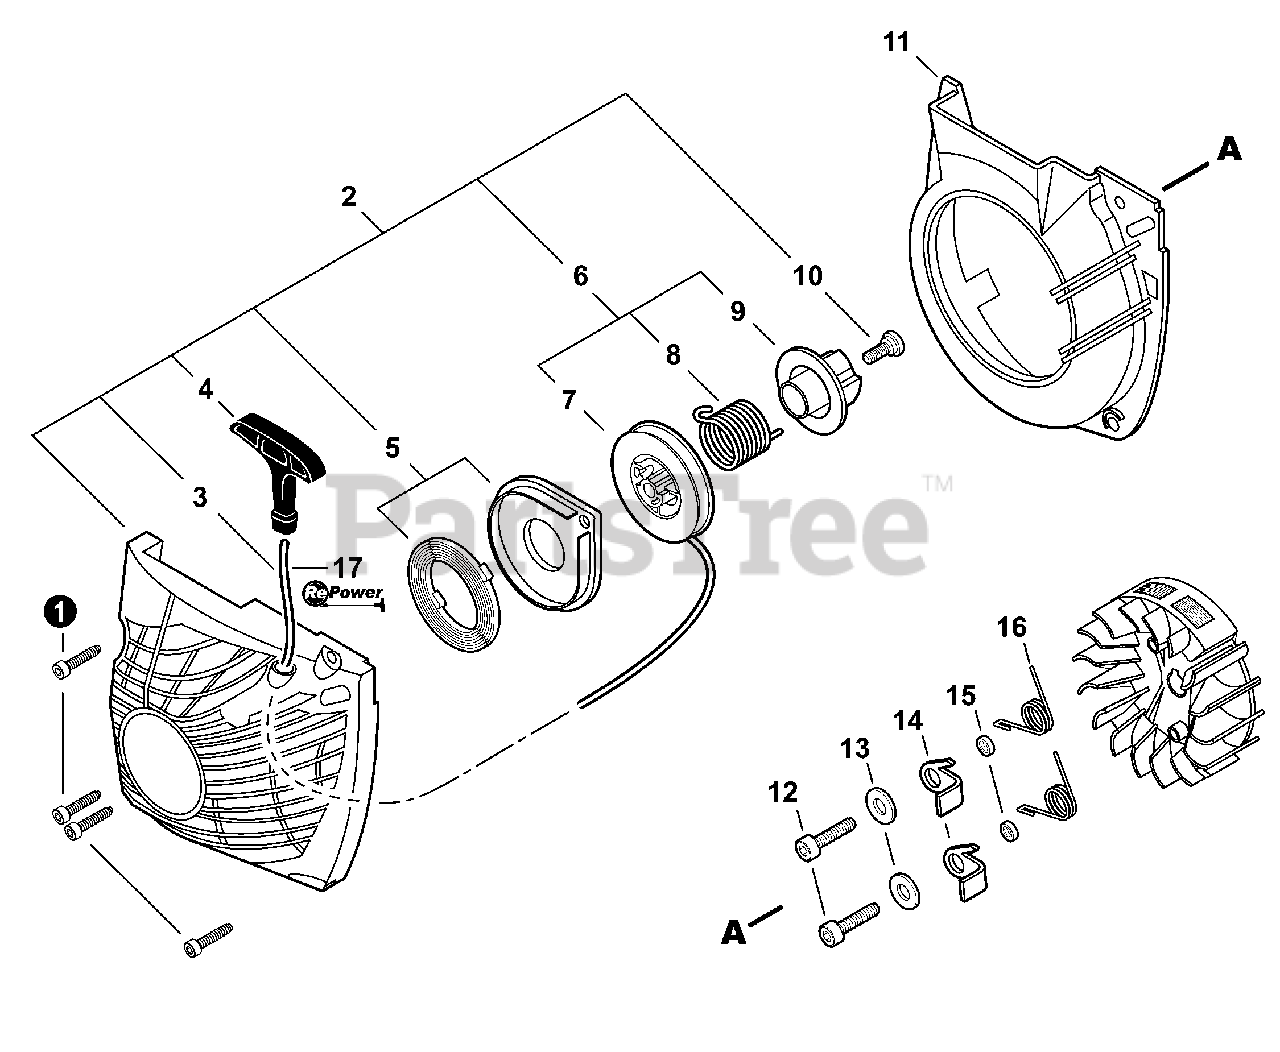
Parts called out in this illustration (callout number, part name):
1	SCREW TAPPING 5×20
2	STARTER ASSY, RECOIL - I-START
3	ROPE, STARTER 3.5×900
4	GRIP, STARTER
5	SPRING SET, RECOIL
6	REEL KIT, ROPE
7	REEL, ROPE
8	SPRING, TORSION
9	PAWL CATCHER
10	SCREW
11	COVER, FAN
12	BOLT 5×14
13	WASHER 5.5×12×0.8
15	SPACER 5.2×8×2.1
16	SPRING, TORSION
17	ROPE, STARTER - REPOWER BULK
